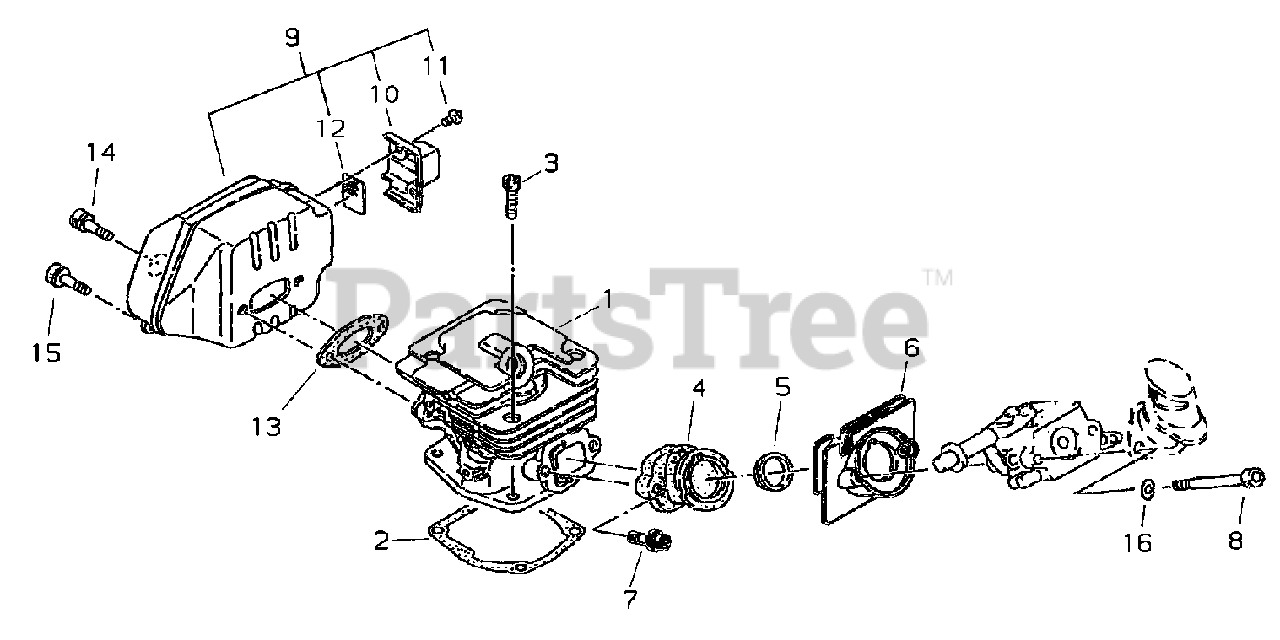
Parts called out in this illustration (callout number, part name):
1	CYLINDER
2	GASKET, CYLINDER
3	SCREW - 5
4	BELLOWS, INTAKE
5	COLLAR - 16
6	INSULATOR, INTAKE
7	SCREW - 4X12
8	SCREW - 5X40
9	MUFFLER ASSY
10	GUIDE, EXHAUST
11	SCREW - 4X6
12	SCREEN, SPARK ARRESTOR
13	GASKET, EXHAUST
14	SCREW - 5X16
15	BOLT - 5
16	WASHER - 5
